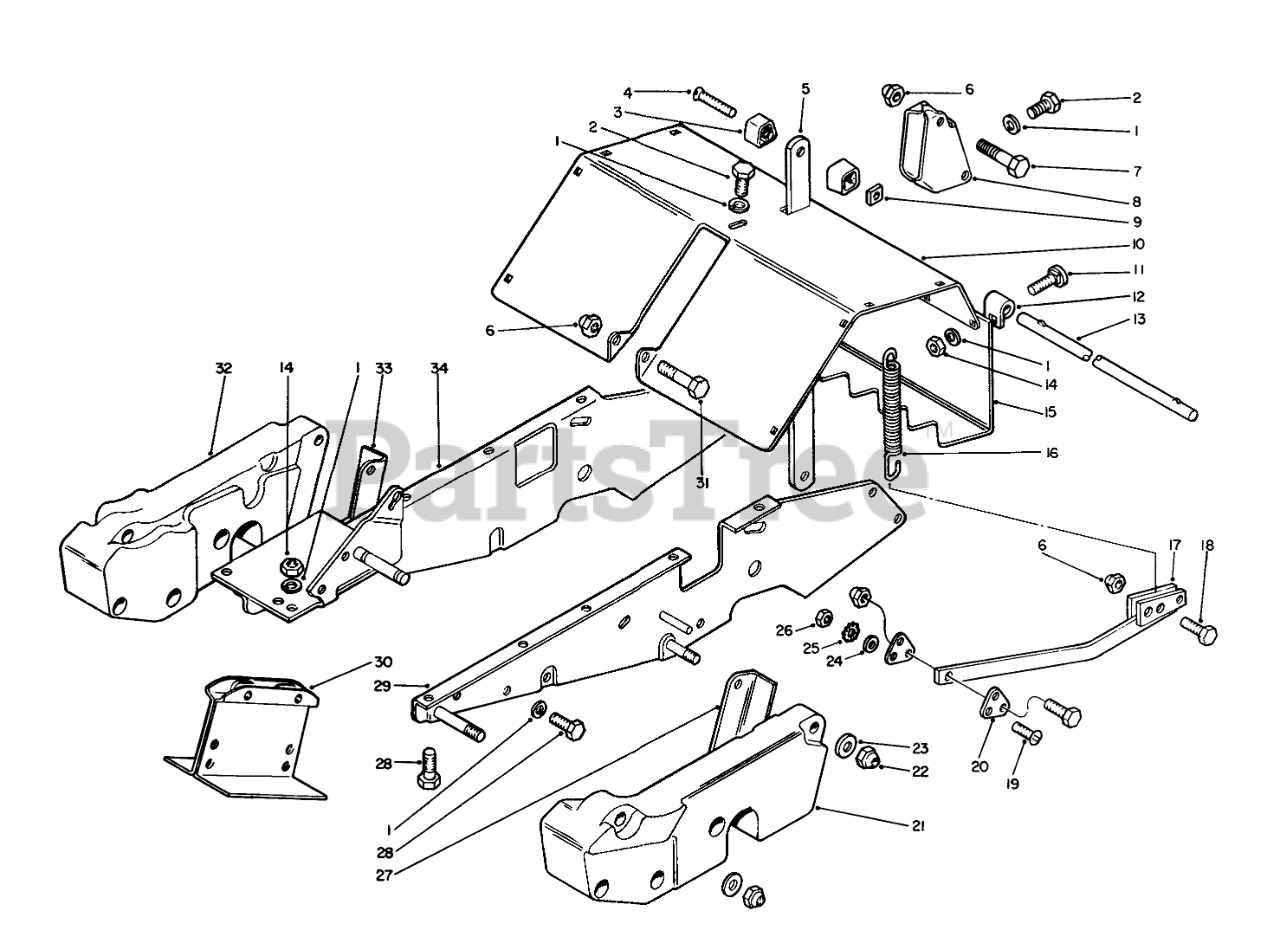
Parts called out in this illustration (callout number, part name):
1	WASHER-LOCK
2	SCREW-HH
3	Handle
4	Machine Screw
5	Depth Control
6	NUT-LOCK, CONE
7	SCREW-HH
8	Support
9	Nut-Square
10	Shield w/Decal
11	BOLT-CARR
12	Hinge
13	Rod
14	NUT-HEX
15	Guard
16	Spring
17	Skid
18	SCREW-HH
19	10-24 X 1 RND HD MS
20	Lug
21	Counterweight-L.H.
22	NUT-LOCK, CONE
23	WASHER-FLAT
24	WASHER-PLAIN
25	WASHER-LOCK, EXT
26	NUT-HEX
27	Hanger-Rear L.H.
28	SCREW-HH
29	Frame-L.H.
30	Support-Counterweight
31	Hex Hd. Capscrew
32	Counterweight-R.H.
33	Hanger-Rear R.H.
34	Frame-R.H.
